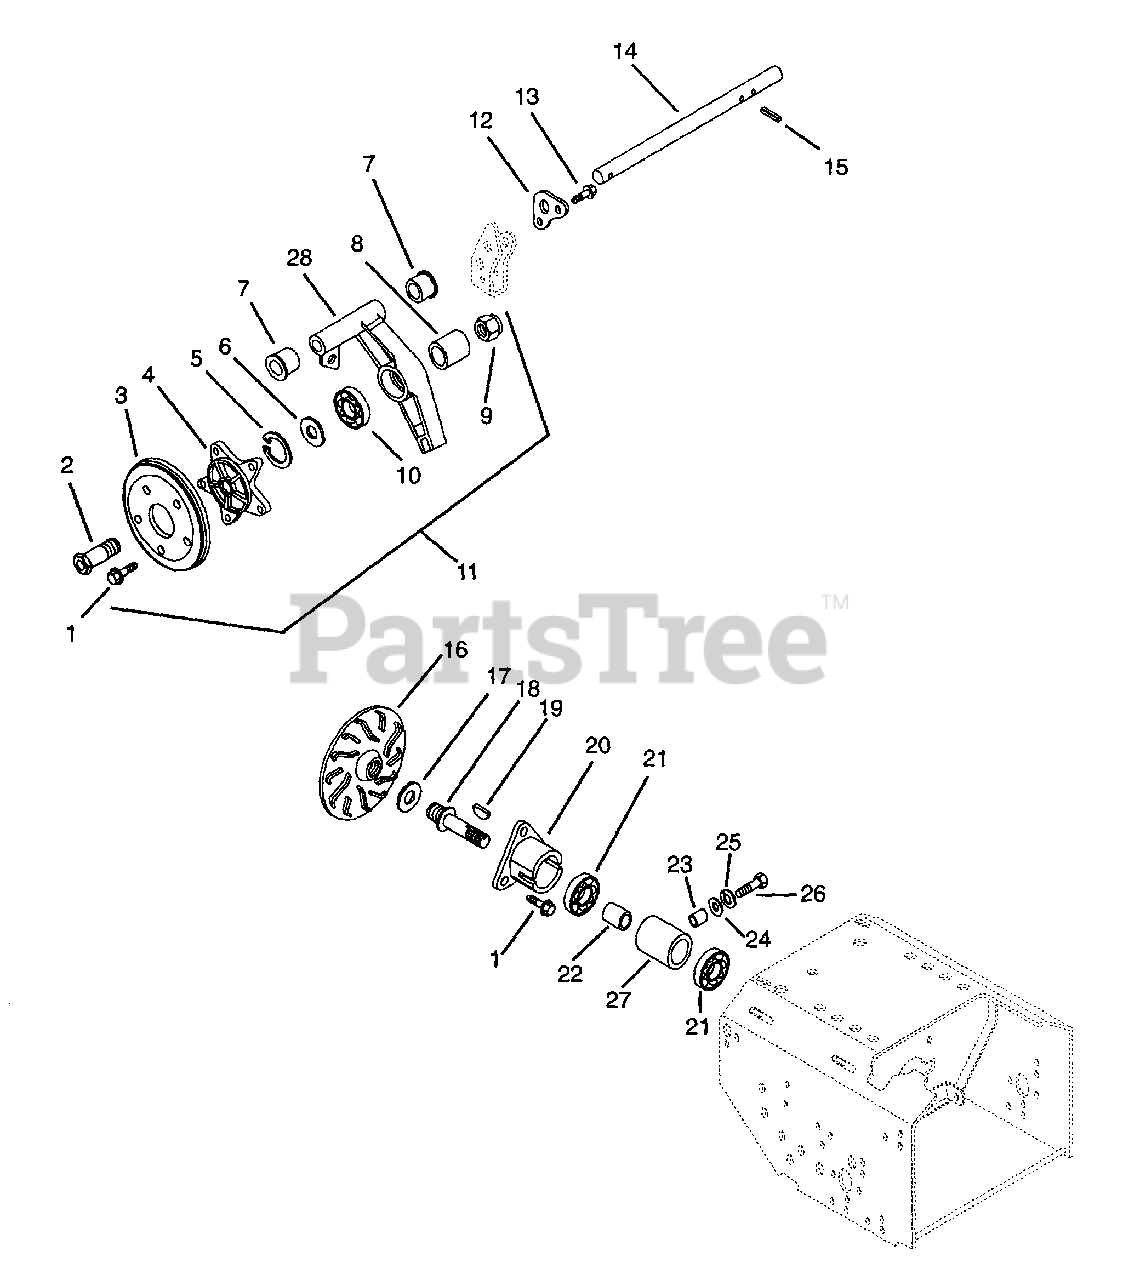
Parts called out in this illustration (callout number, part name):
1	@SCR-TAP .31-18X.50 HWH TR YWZ
2	SPINDLE HUB
3	FRICTION DISC
4	DISC HUB
5	RG-RTNG-INT 1.750X.062
6	WSHR-FL-STL .880X1.250X.062
7	BSHG-FLG .625X.750X.500X.875BR
8	BSHG-SLV .882X1.250X.531
9	NUT-LK-NYL .875-14 YWZC
10	BRG-BALL .876 X 1.750 X .50
11	FRICTION WHEEL ASSEMBLY
12	SUPPORT, SHAFT
13	@SCR-TAP .25-20X.50 HWH TR YWZ
14	CARRIER SHAFT
15	PIN-ROLL .156X1.00
16	DRIVE PLATE
17	DRIVE DISC SPACER 1.3X.76X.19
18	SPINDLE
19	KEY-WDRF .125X.500X.203 SAE 3
20	HOUSING MOUNT
21	BRG-BALL .625X1.375X.44
22	BEARING SPACER
24	@WSHR-FL-STL.344X.688X.065YWZC
25	WSHR-LK .312X.097 HVY YWZC
26	@BLT-HEX .31-18X1.00 GR5 YWZC
27	SPINDLE HOUSING
28	CARRIER
